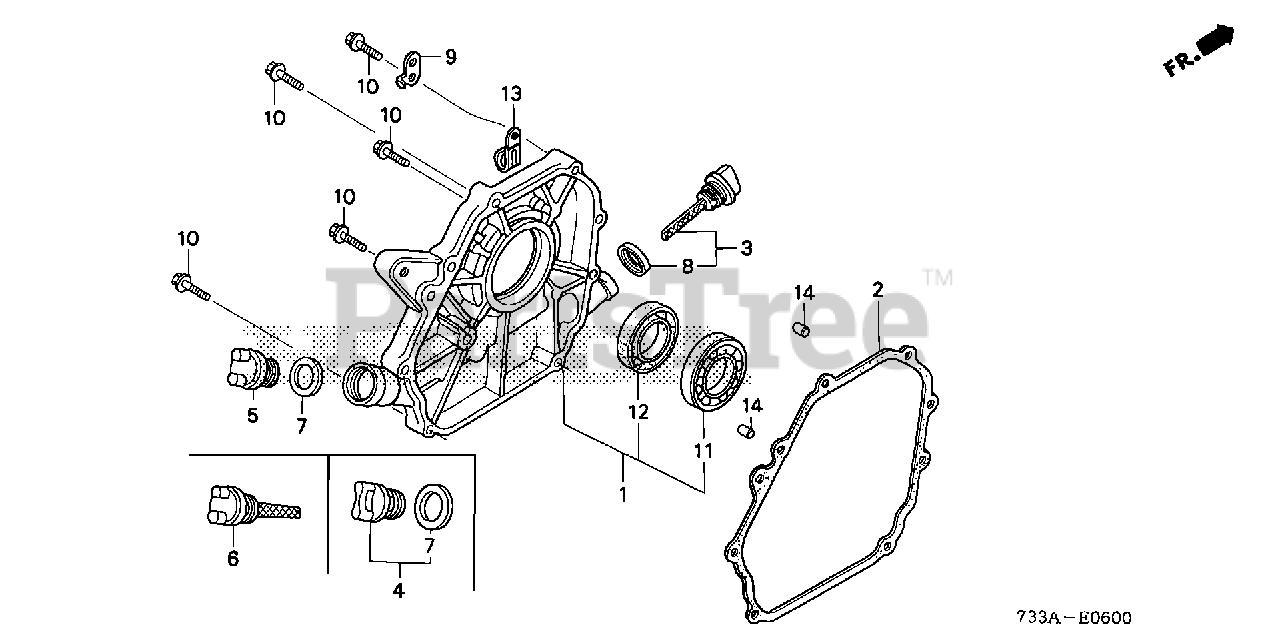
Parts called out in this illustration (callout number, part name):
1	COVER ASSY., CRANKCASE
2	GASKET, CASE COVER
3	CAP ASSY., OIL FILLER (GRAY)
5	CAP, OIL FILLER
6	CAP, OIL HOLE
7	GASKET, OIL FILLER CAP
8	GASKET, OIL FILLER CAP
9	STAY, WIRE CLIP
10	BOLT, FLANGE (6X28) (CT200)
11	BEARING, RADIAL BALL
12	OIL SEAL (22X41X6)
13	CLIP, WIRE HARNESS
14	PIN, DOWEL (8X14)
